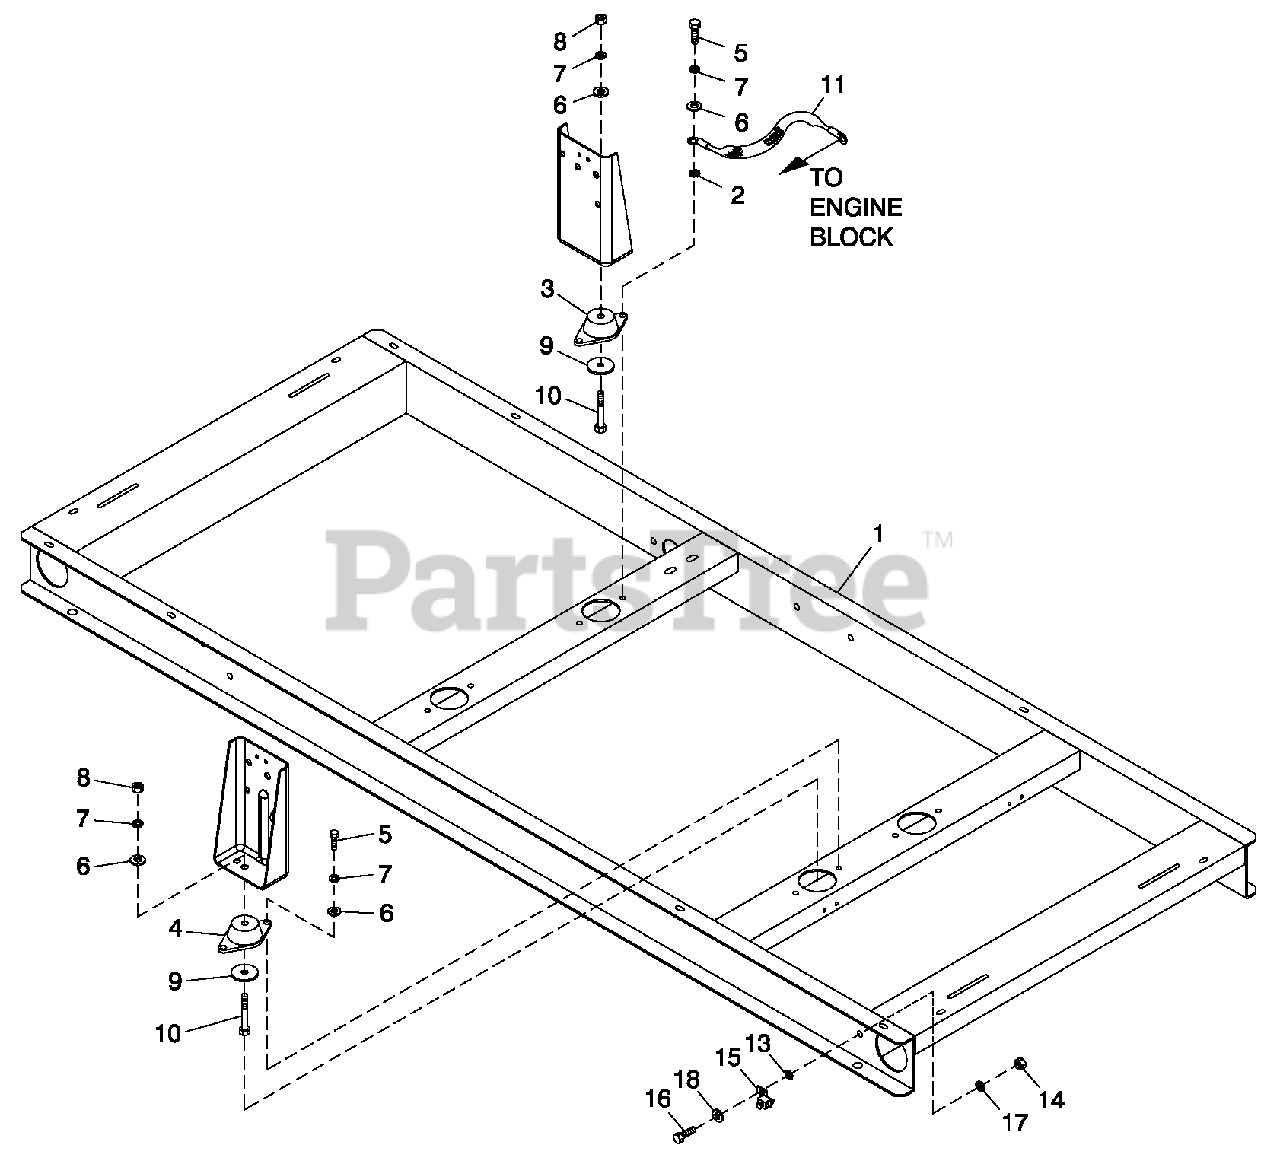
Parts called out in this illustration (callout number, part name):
1	MOUNTING BASE 1.5L C1 CPL
2	WASHER SHAKEPROOF EXT 5/16 STL
3	DAMPENER VIBRATION
4	VIB. ISO. 70'75 DURO
5	SCREW HHC M8'1.25 X 20 G8.8
6	WASHER FLAT 5/16 ZINC
7	WASHER LOCK M8'5/16
8	NUT HEX M8'1.25 G8 YEL CHR
9	WASHER FLAT M8
10	SCREW HHC M8'1.25 X 60 G8.8
11	EARTH STRAP
13	WASHER SHAKEPROOF EXT 1/4 STL
14	NUT HEX M6 X 1.0 G8 YEL CHR
15	LUG SLDLSS #2'#8 X 17/64 CU
16	SCREW HHC M6'1.0 X 16 G8.8
17	WASHER LOCK M6'1/4
18	WASHER FLAT 1/4'M6 ZINC
